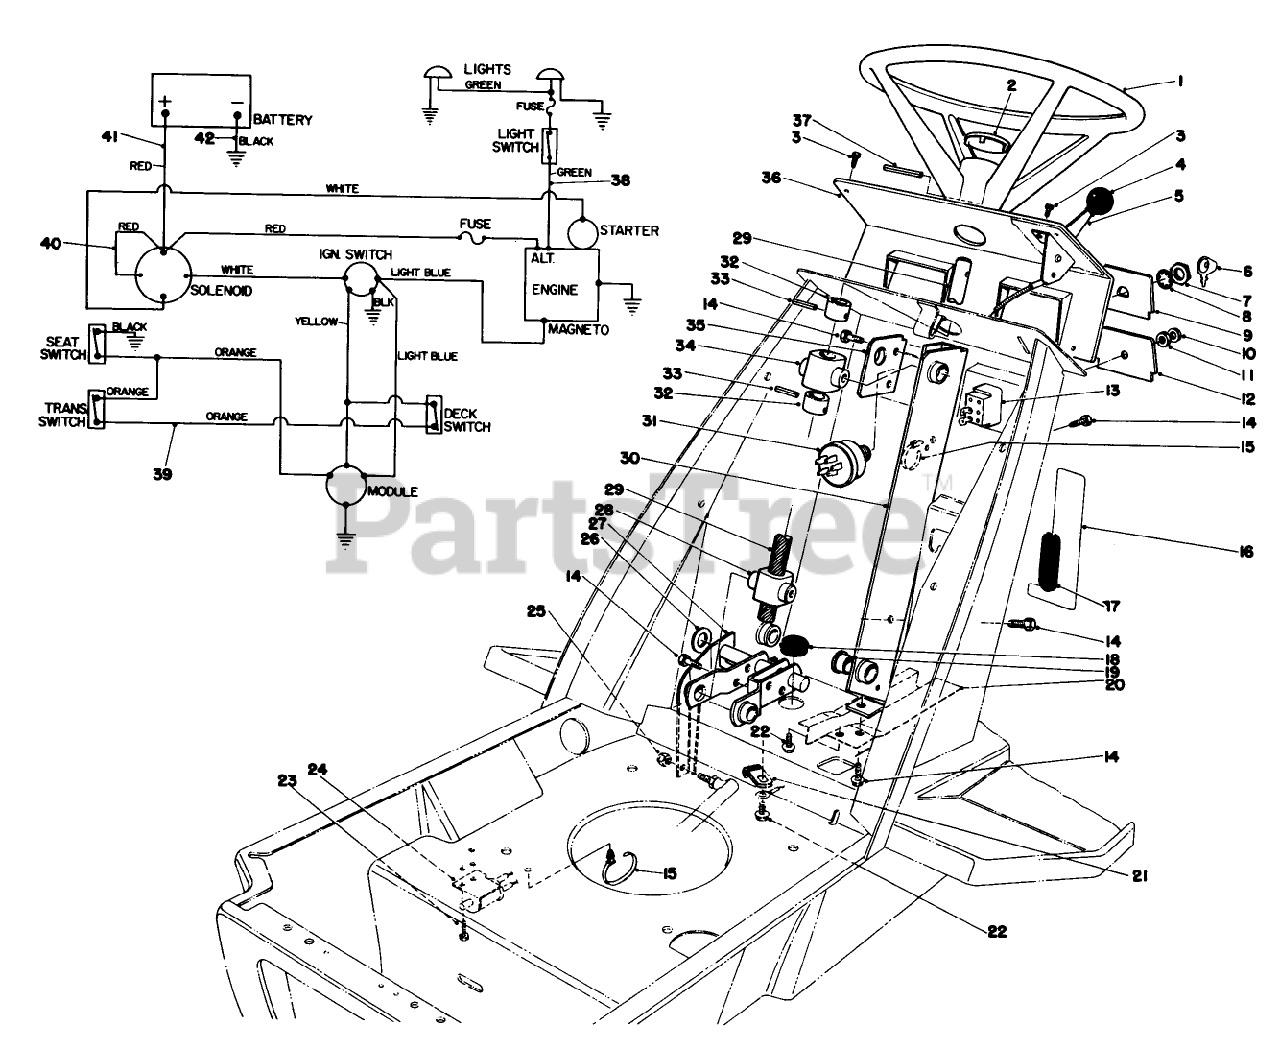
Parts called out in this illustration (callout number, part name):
3	SCREW-HWHTF
4	KNOB-CONTROL
5	THROTTLE CONTROL
8	WASHER-LOCK
11	Locknut
13	SWITCH-LIGHT
14	SCREW-THD ROLL, HWH
15	TIE-MOUNT, PUSH
18	GROMMET
19	BEARING-FLANGE
21	CLIP-FUEL LINE
22	SCREW-HWH
23	SCREW-TAPTITE
29	STEERING SHAFT
31	SWITCH-STARTER
32	STRG SHAFT COLLAR
33	PIN-SPRING
37	PIN-ROLL
41	WIRE ASM
42	WIRE ASM
